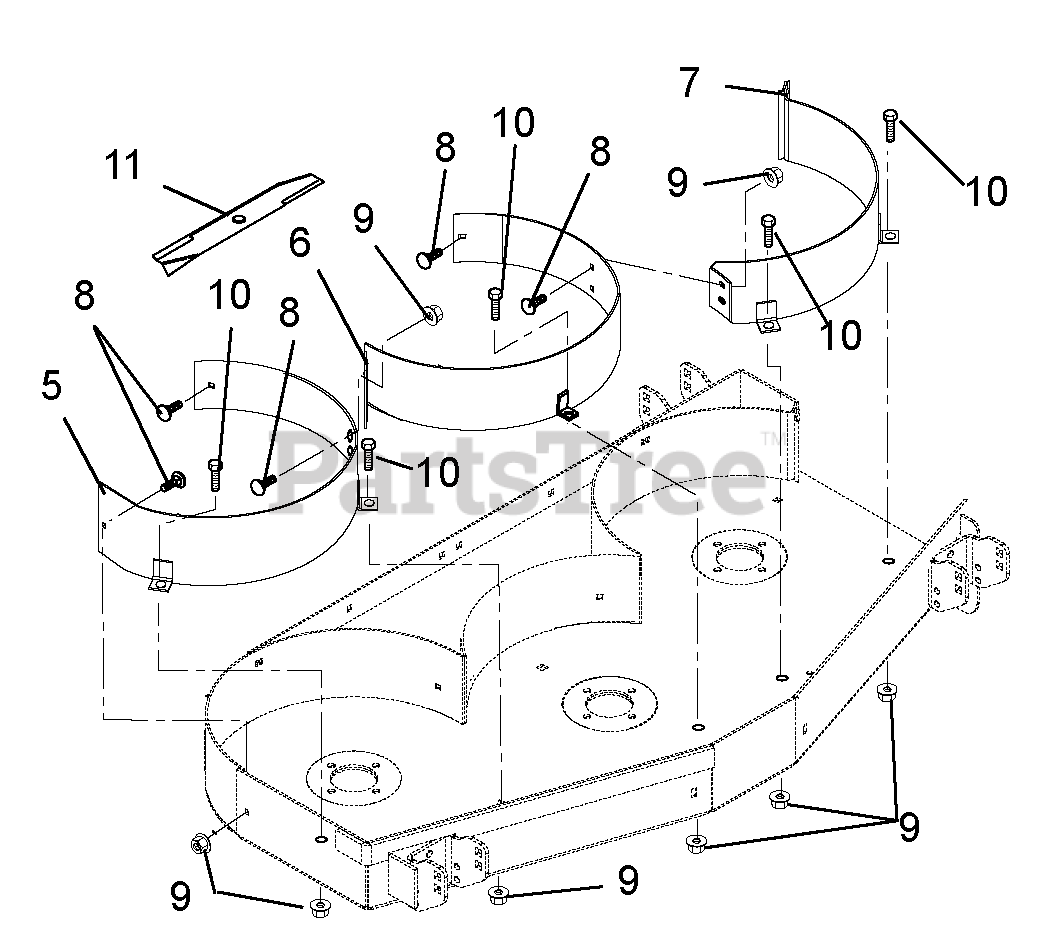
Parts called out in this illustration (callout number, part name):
5	32" Left Mulch Baffle
5	36" Left Mulch Baffle
5	44" Left Mulch Baffle
5	48" Left Mulch Baffle
5	52" Left Mulch Baffle
5	34" Left Mulch Baffle
6	44" Center Mulch Baffle
6	48" Center Mulch Baffle
6	52" Center Mulch Baffle
7	32" Right Mulch Baffle
7	36" Right Mulch Baffle
7	44" Right Mulch Baffle
7	48" Right Mulch Baffle
7	52" Right Mulch Baffle
7	34" Right Mulch Baffle
8	Round Head Square Neck Bolt, 5/16-18 x 3/4
9	Top-Locking Flange Nut, 5/16-18
10	Hex Bolt, 5/16-18 x 3/4
11	Blade, Mulch
11	Mulch Blade
